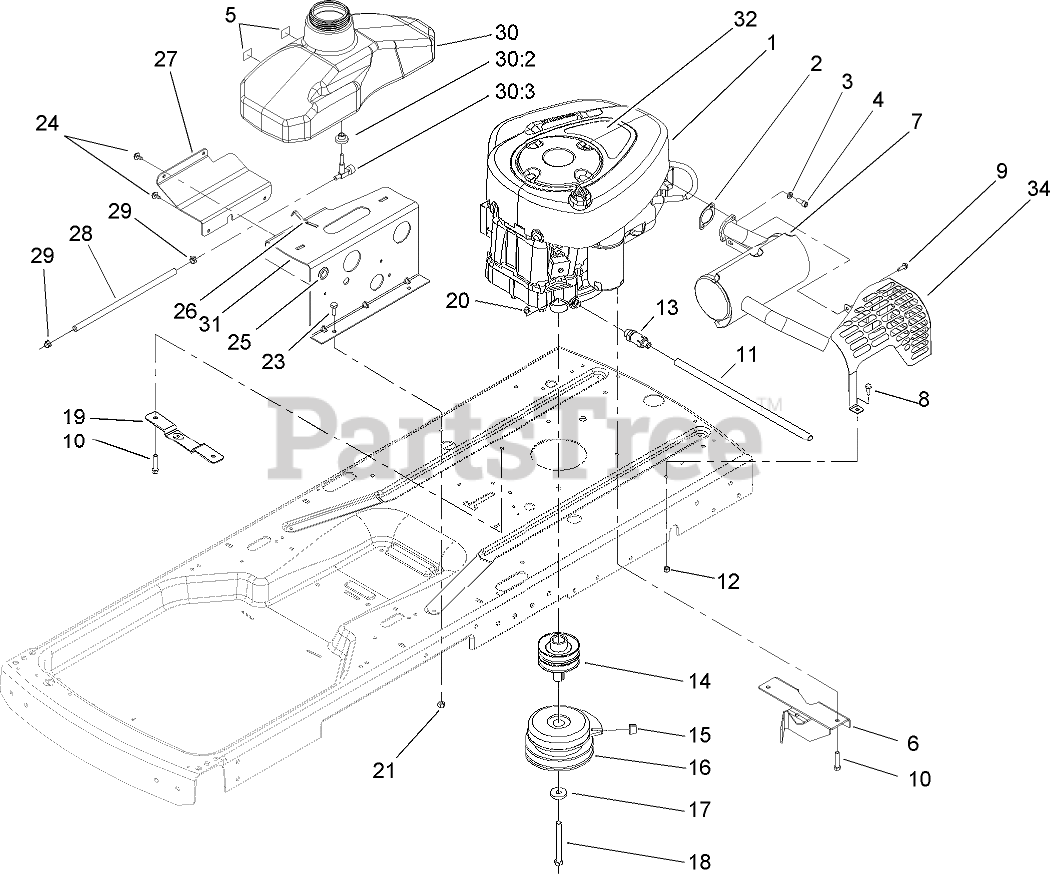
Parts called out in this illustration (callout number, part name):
2	GASKET-EXHAUST
3	WASHER-LOCK
4	SCREW-HSH
5	FOAM-SWITCH, SEAT
6	BRACKET-PIVOT
7	MUFFLER
8	SCREW-HH
9	SCREW-HWH, THREAD ROLL
10	SCREW-HH
11	TUBE-DRAIN, OIL
12	NUT-LOCK, NI
13	VALVE-DRAIN, OIL
14	PULLEY-ENGINE
15	BUMPER
16	CLUTCH-ELECTRIC
17	WASHER
18	SCREW-HH
19	PLATE-MOUNT, IDLER
20	NUT-HF
21	NUT-LOCK, NI
23	SCREW-HH
24	SCREW-HHFTF
25	GROMMET
26	SPRING
27	PLATE-SUPPORT
28	HOSE-FUEL
29	CLAMP-HOSE
30	GAS TANK ASM
30:2	BUSHING
30:3	VALVE-FUEL
31	PLATE-TANK
34	GUARD-MUFFLER
